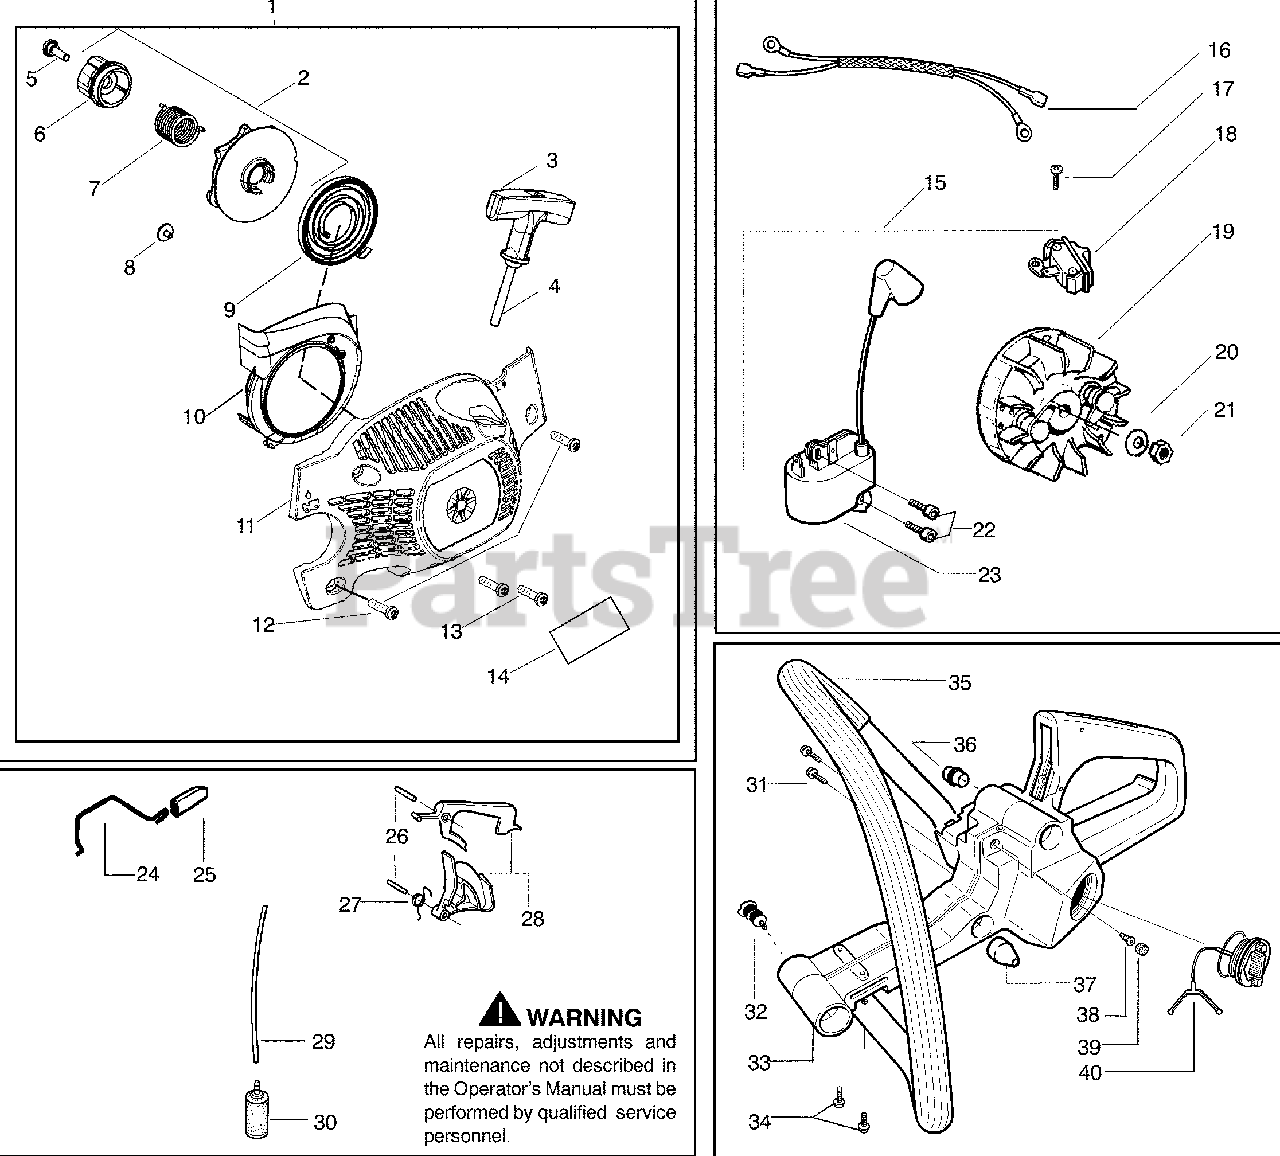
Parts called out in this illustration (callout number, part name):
1	Kit--Fan Hsg / Starter
2	Kit--Starter EPS
3	Handle--Starter
4	Kit--Rope
5	Screw--shoulder
7	Spring--EPS
9	Spring--Starter
10	Baffle--Air
11	Assy--Fan Hsg. w/eyelet
14	Decal--Fan Housing
15	Kit--EPS ignition
16	Assy--Leadwire
18	Switch--Ignition
19	Assy. --Flywheel
20	Washer--Flywheel
23	Module -- Ignition
24	Wire -- Throttle
25	Cap -- Wire
28	Kit -- Throttle Trigger
29	Kit -- Fuel line
30	Assy.-- Fuel Pickup
32	Element -- AV Isolator
33	Assy. --Tank/Handle
35	Handle--Front
36	Isolator--Front Handle
38	Valve -- Check
39	Plug -- Vent
40	Kit--Assy. Fuel Cap
